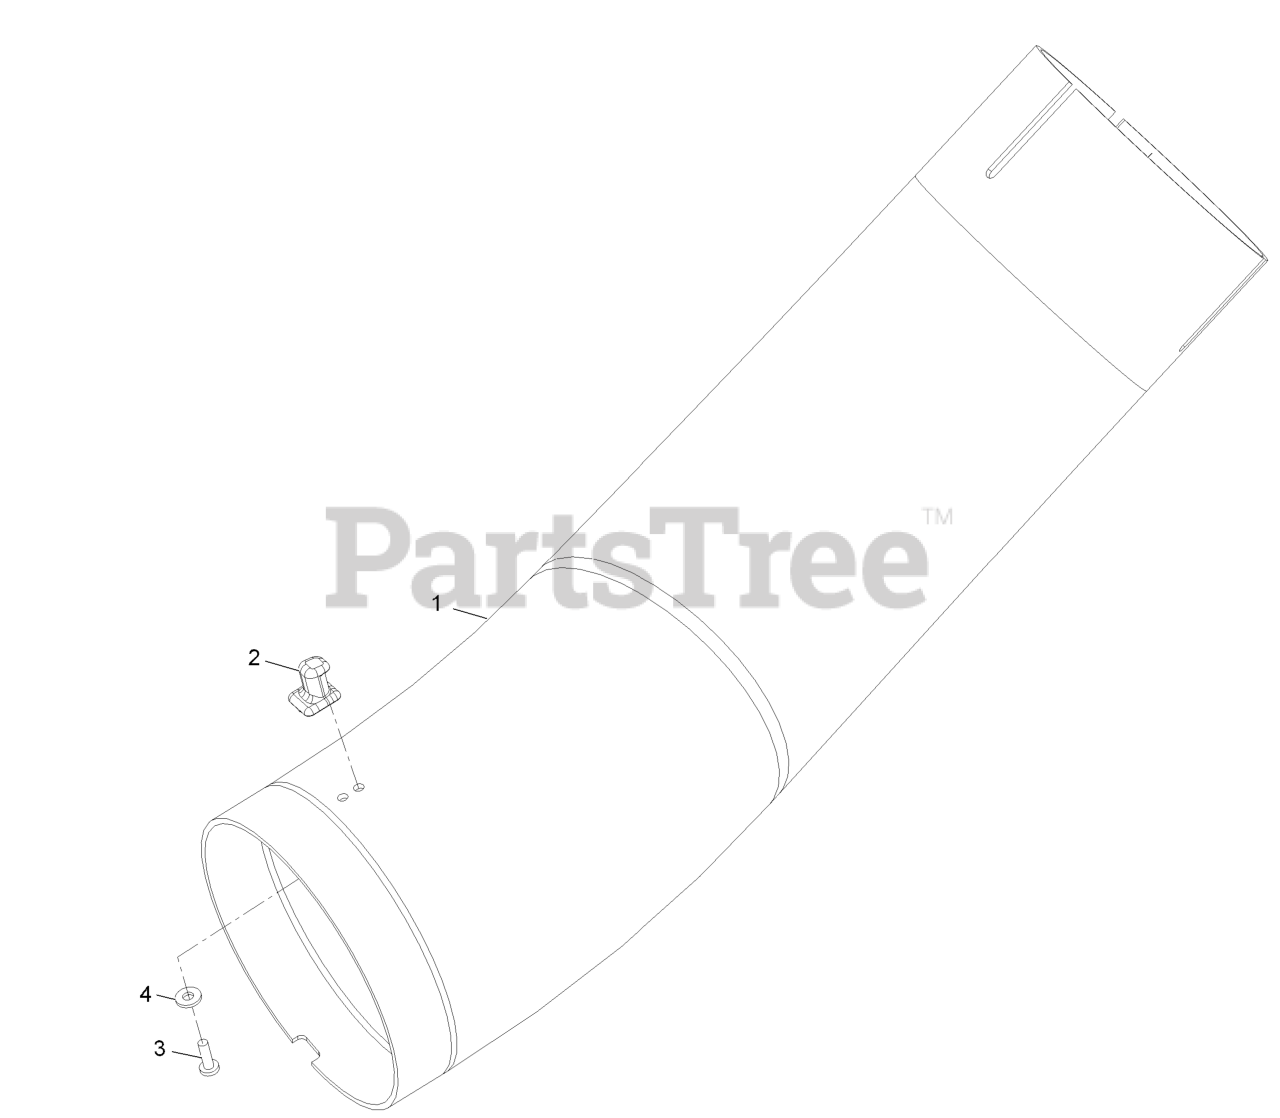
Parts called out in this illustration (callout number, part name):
1	Tube,Lower Short
2	LATCH-KEEPER
3	SCREW-PPH
4	WASHER-FLAT
